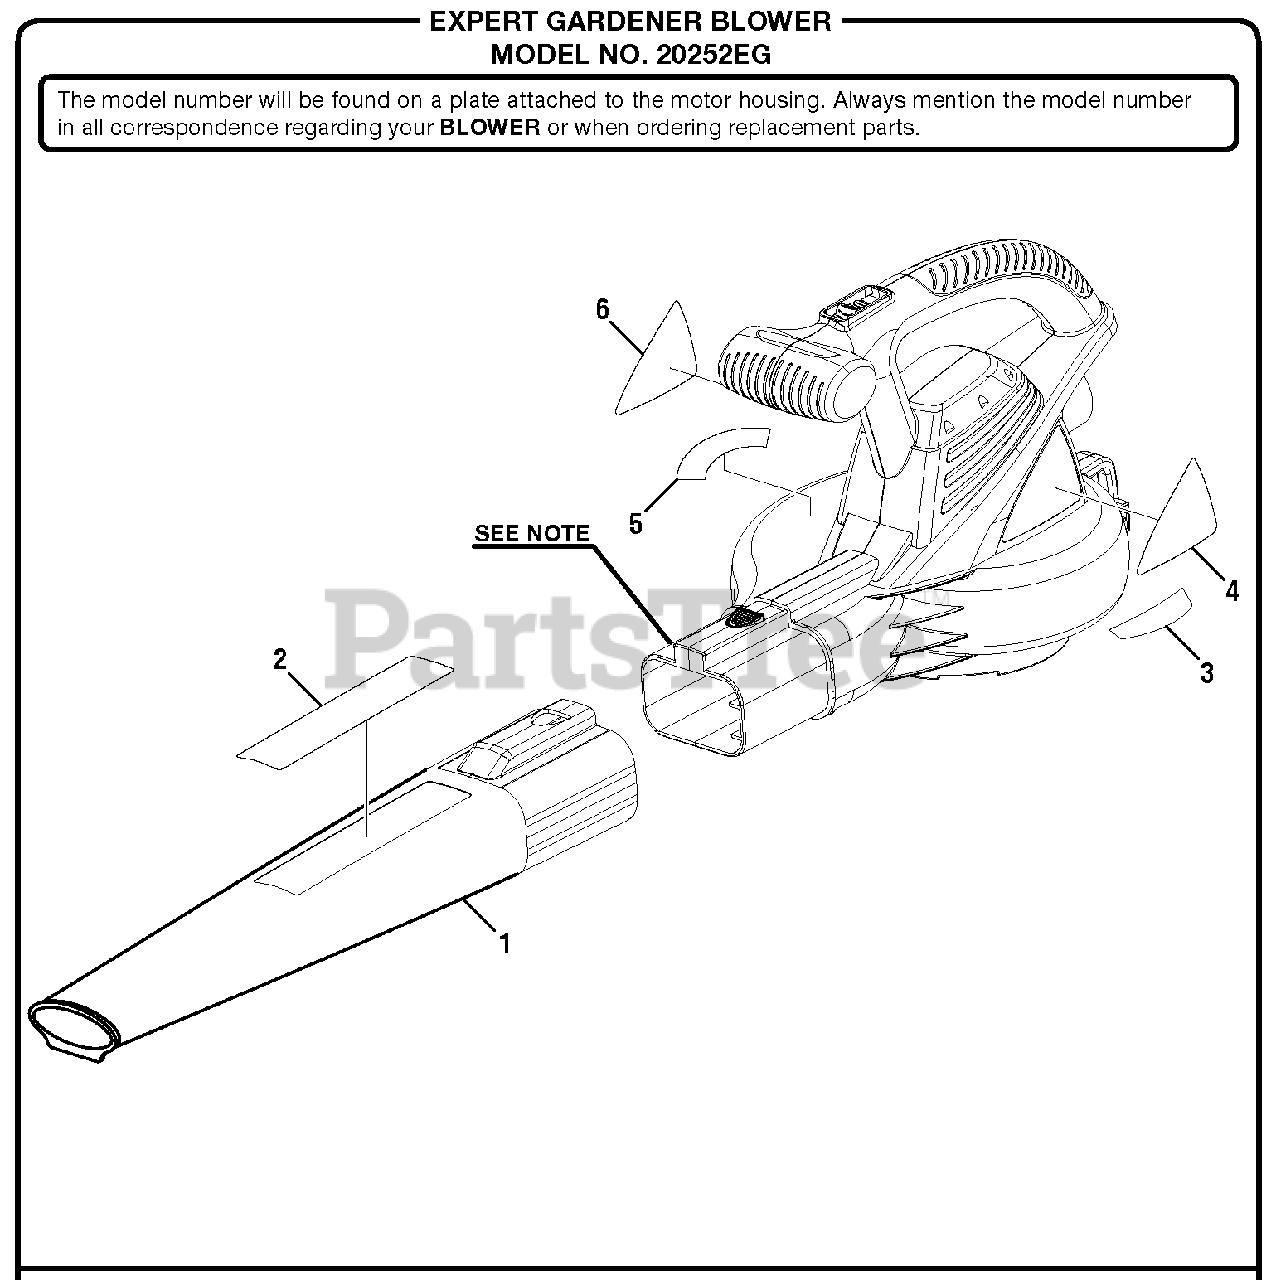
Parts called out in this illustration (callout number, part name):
1	Blower Tube
2	Blower Tube Label
3	Data Label
4	Warning Label
5	Warning Icon Label
6	Logo Label
